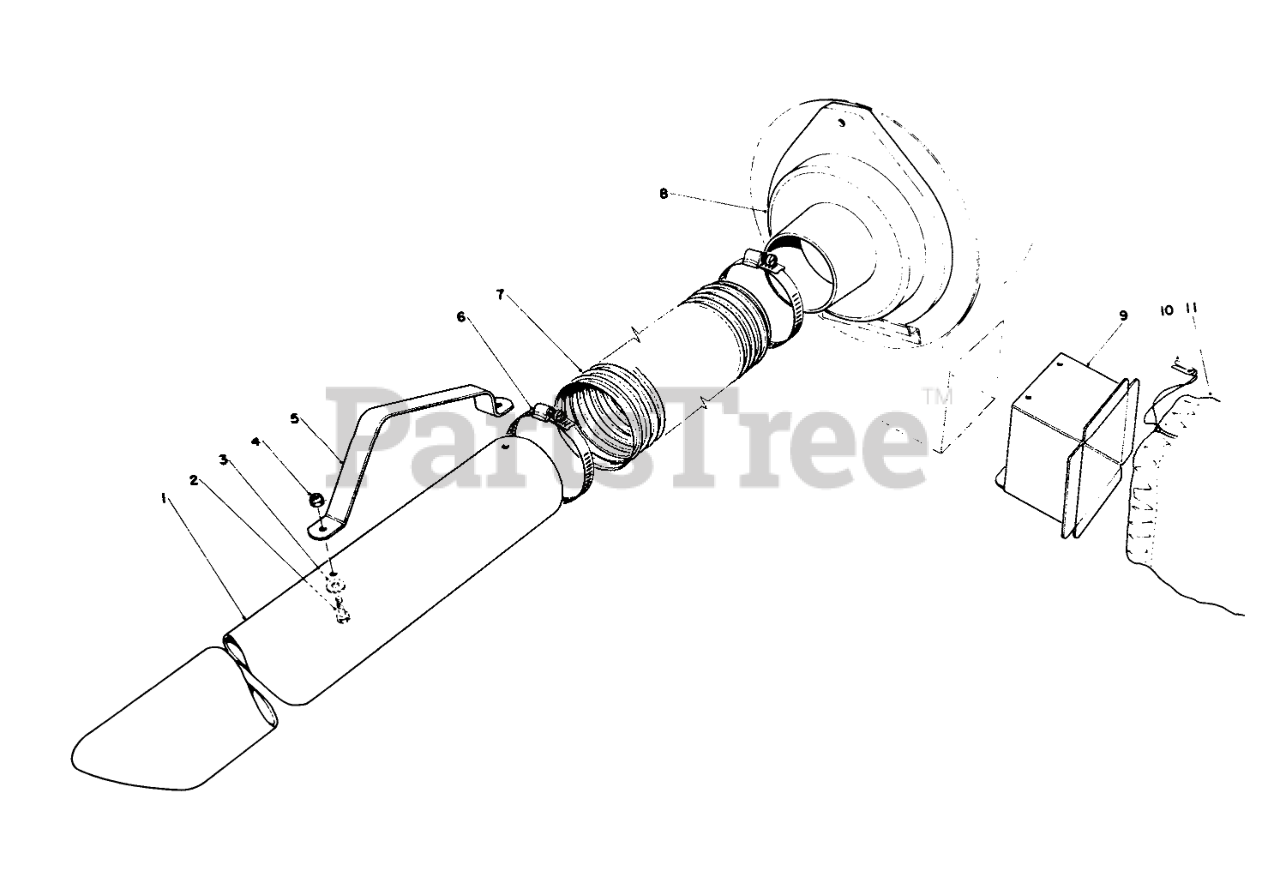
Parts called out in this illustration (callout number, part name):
1	NOZZLE
2	SCREW-HH
3	SPECIAL WASHER
4	NUT-KEPS
5	NOZZLE HANDLE
6	Clamp
7	VACUUM HOSE
8	ADAPTOR HOSE TO HSG
9	HOUSING WA BLOWER BAG
10	BAG CORD FASTENER
11	Bag
